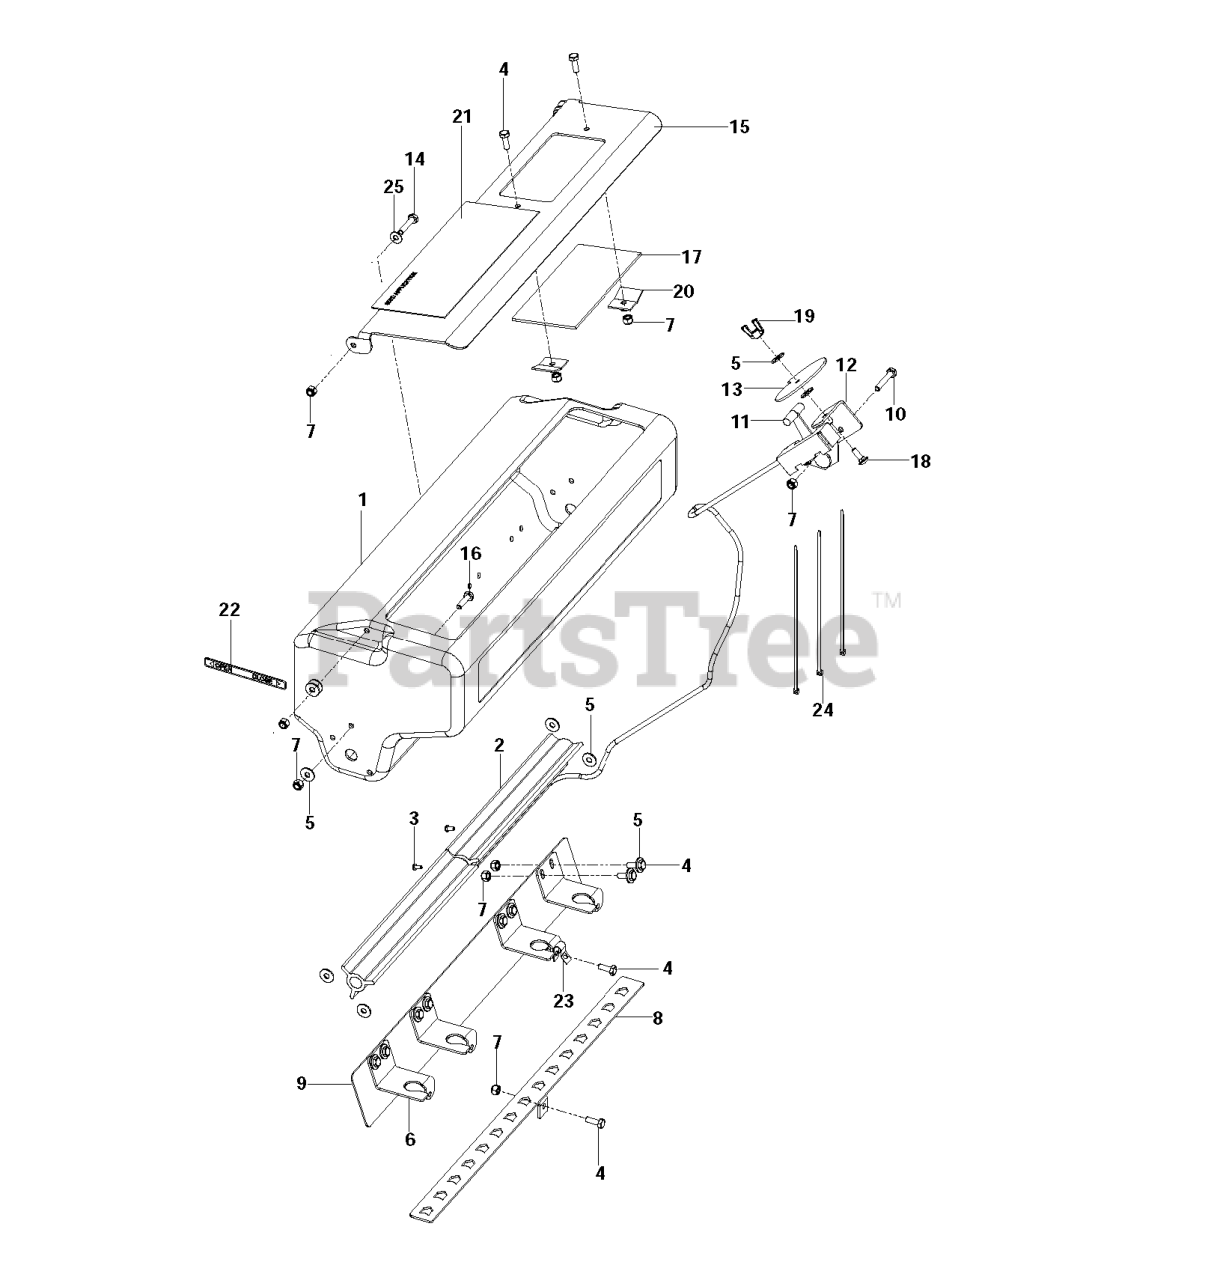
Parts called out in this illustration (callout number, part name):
1	SEED BOX CHARCOAL GREY
3	SCREW - #8-32 X 3/8
4	HCS 1/4C X 3/4 HCS
5	WASHER 1/4 FLAT
7	NUT.1/4-20.HEX.NYLOC.ZD
10	SCW 1/4-20 X 1-1/2 HEX
11	CONTROL, PUSH/PULL ASSEMBLY
14	BOLT HEX 1/4 X 1-1/4
15	SEED DOOR ORANGE
16	HCS 1/4 X 1
17	SEED WINDOW
18	RHSNB 1/4C X 3/4
19	WING NUT 1/4
20	WINDOW CLIP
21	DECAL, SEED APPL
22	DECAL, OPEN/CLOSE
23	BRACKET, PUSH/PULL
24	TIE, PLASTIC
25	WASHER 1/4 SAE
